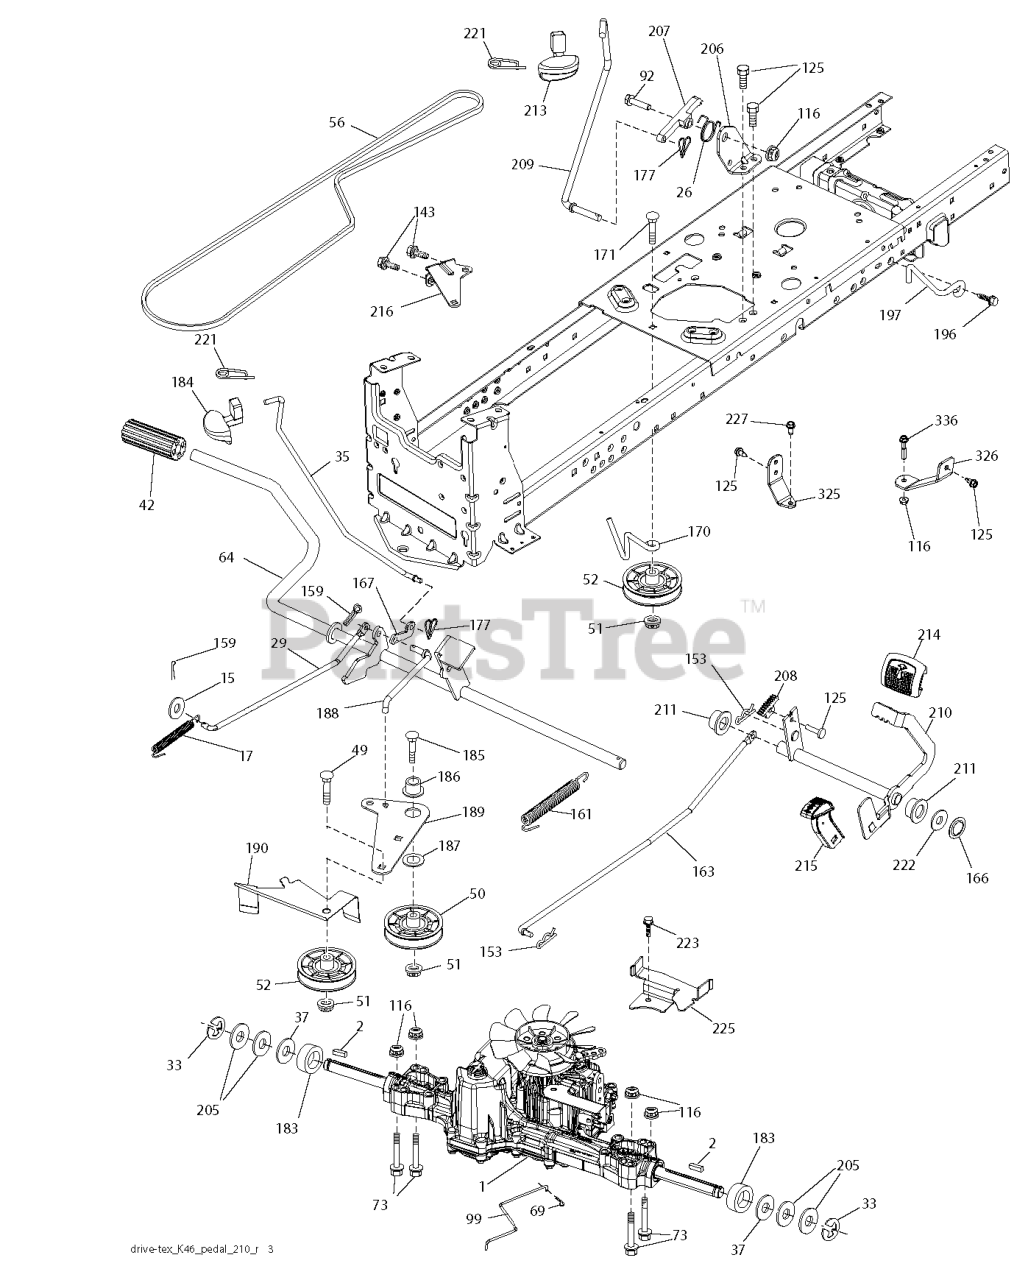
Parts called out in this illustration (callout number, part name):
2	SQUARE KEY
15	WASHER PLAIN WASHER 3/8 X 0.08
17	SPRING.BRAKE.K46.GREEN
26	SPRING.RETURN.CRUISE
29	ROD.BRAKE.K46
37	WASHER.HARDENED
42	PEDAL COVER
50	IDLER.FLAT.910.OFFSET
51	NUT LOCK FLG 3/8-16 UNC
52	IDLER.V-GROOVE.910.OFFSET
64	SHAFT.ASM.PEDAL.BRK.CNTR
69	HAIRPIN.SOFT.ZINC.059X1.125
99	ARM.PIVOTING.TCRD.GEN2.5.BAGGE
125	SCREW
153	RETAINER M
161	SPRING, RETURN LT
166	NUT.PUSH.625
167	LATCH.BRAKE.SPRING
170	KEEPER.V-IDLER.CENTER.
177	GSPW Retainers
177	PIN COTTER;LOCKING;BOWTIE;1IN
183	SPACER AXLE
184	HANDLE.PARKING.BRAKE.H (BLK)
186	SPACER.RETAINER
188	LINK.CLUTCH.GROUND DRIVE.LONG
189	BELLCRANK.GROUND.DRIVE.TEX.
190	KEEPER.BELLCRANK.DRIVE
196	SCREW 3/8-16X1
206	BRACKET.MOUNT.CRUISE.LATCH
210	ROCKER.ASM.PEDAL.CONTR
211	BEARING.NYLON
213	KNOB.CONTROL.CRUSIE.HU
214	PEDAL.FORWARD.PAD.TEX
215	PEDAL.COVER.REVERSE.CRD.X428BK
216	BRACKET.PULLEY.IDLER.W/TEX
221	RETAINER.SPRING.CLIP.H
222	WASHER 21/32 X 1-1/4 X 10 GA.
225	KEEPER.BELT.TRANSAXLE.K46
325	BRACKET.TRQ.STP.46.20".TIRE.LH
326	BRCKT.PNT.TRQ.STP.46.20TIRE.RH
